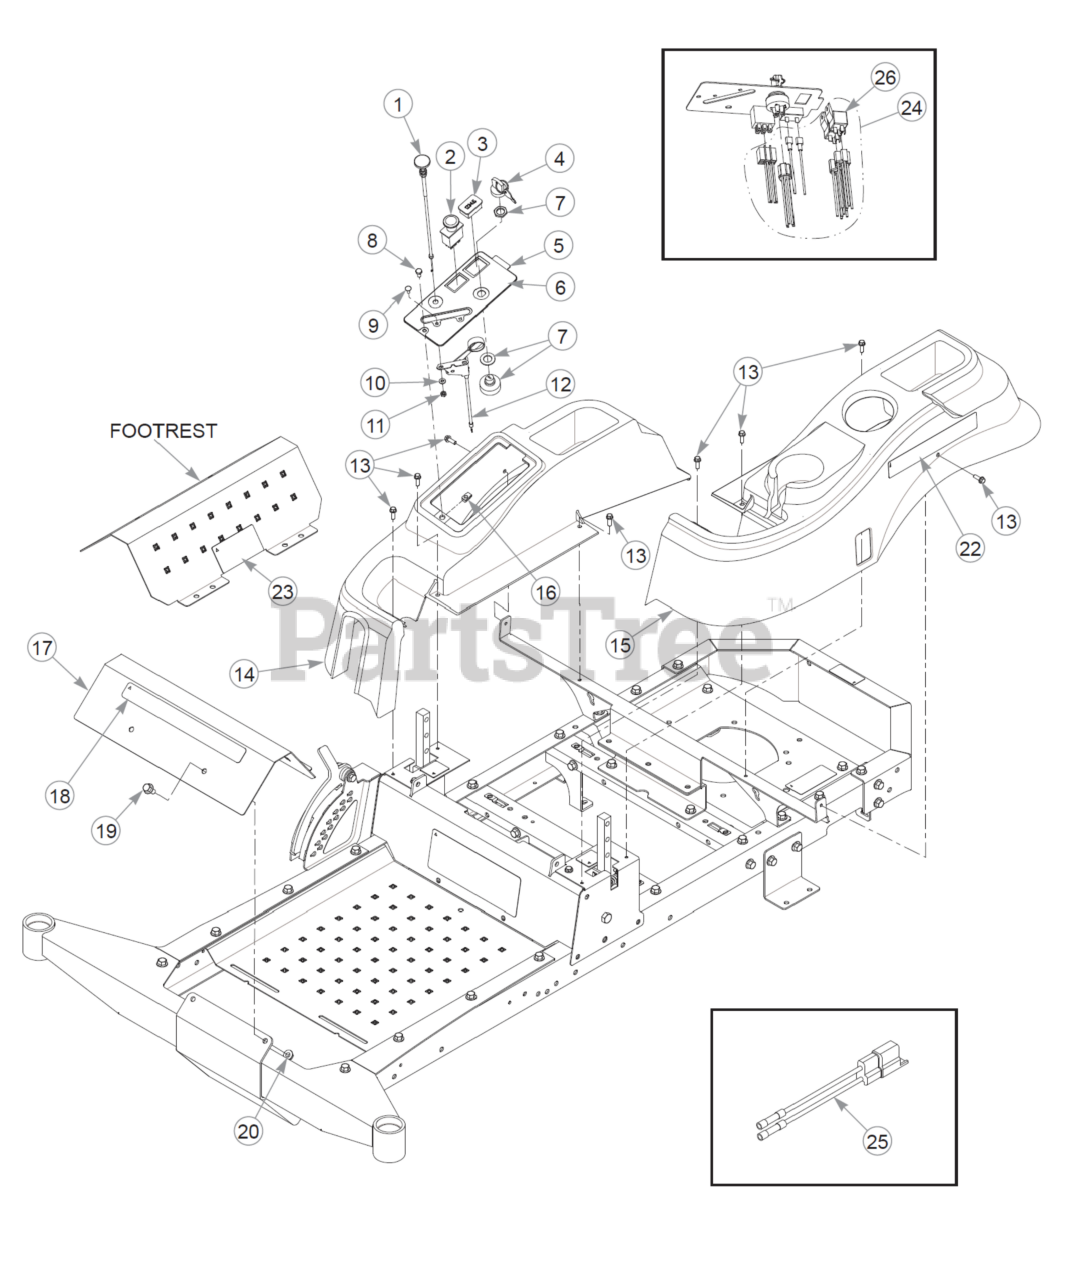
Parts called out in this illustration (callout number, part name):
1	CABLE, CHOKE
2	SWITCH, PTO 6201-321
3	HOUR METER
4	KEY ASSEMBLY
5	SERVICE, INSTR PANEL
6	DECAL, INSTRUMENT PANEL
7	IGNITION SWITCH
8	CS .250-20X0.75 HX G5 ZN
9	CB 10-24 X .500 ZYNC
10	FW 0.219X.50X.05 ZN
11	NT #10-24 HX NL ZN
12	CABLE, THROTTLE
13	CS .250-20 X .75 HX FLG
14	SVC, FENDER RS
15	SVC, FENDER LS
16	CN .250-20X .150 MAX THK
17	SVC, FOOTREST
18	DECAL, HUSTLER ID
19	CS .375-16X0.75 HXF G5ZN
20	NT .375-16 FLKG5
21	WIRE TIE, SMALL/SHORT
22	DECAL, RAPTOR FENDER
23	DECAL, PUMP BELT WARNING
24	WIRE HARNESS
25	KIT, CLUTCH CONN. REP.
26	RELAY, SEALED W/BRACKET
